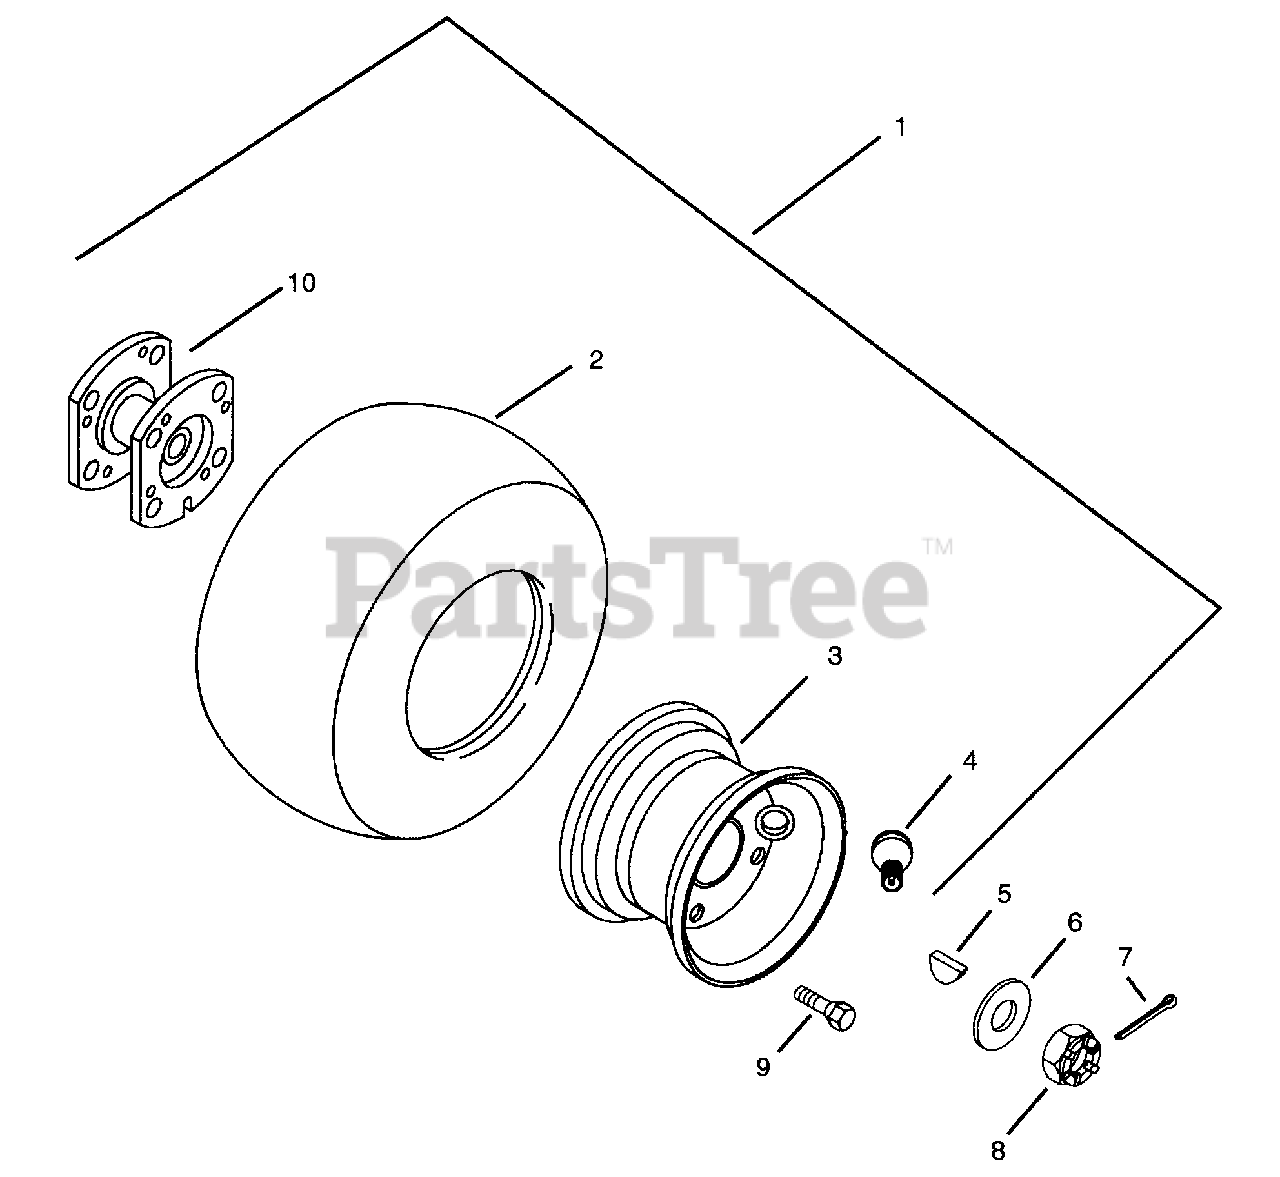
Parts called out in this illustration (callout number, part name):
1	Tire Wheel assembly 16 x 6.50-8
2	Tire 16 x 6.50-8
3	Assembly, Rim
4	Valve Stem Assembly
5	Key-Woodruff .25 x 1.00 x 7.00
6	Washer-Flat-Steel .813 x 1.370 x .100
7	Pin-Cotter .12 x 1.25
8	Nut-Hex-Slotted .75-20
9	Bolt .44-20 x 1.0
10	Weldment, Wheel Hub
